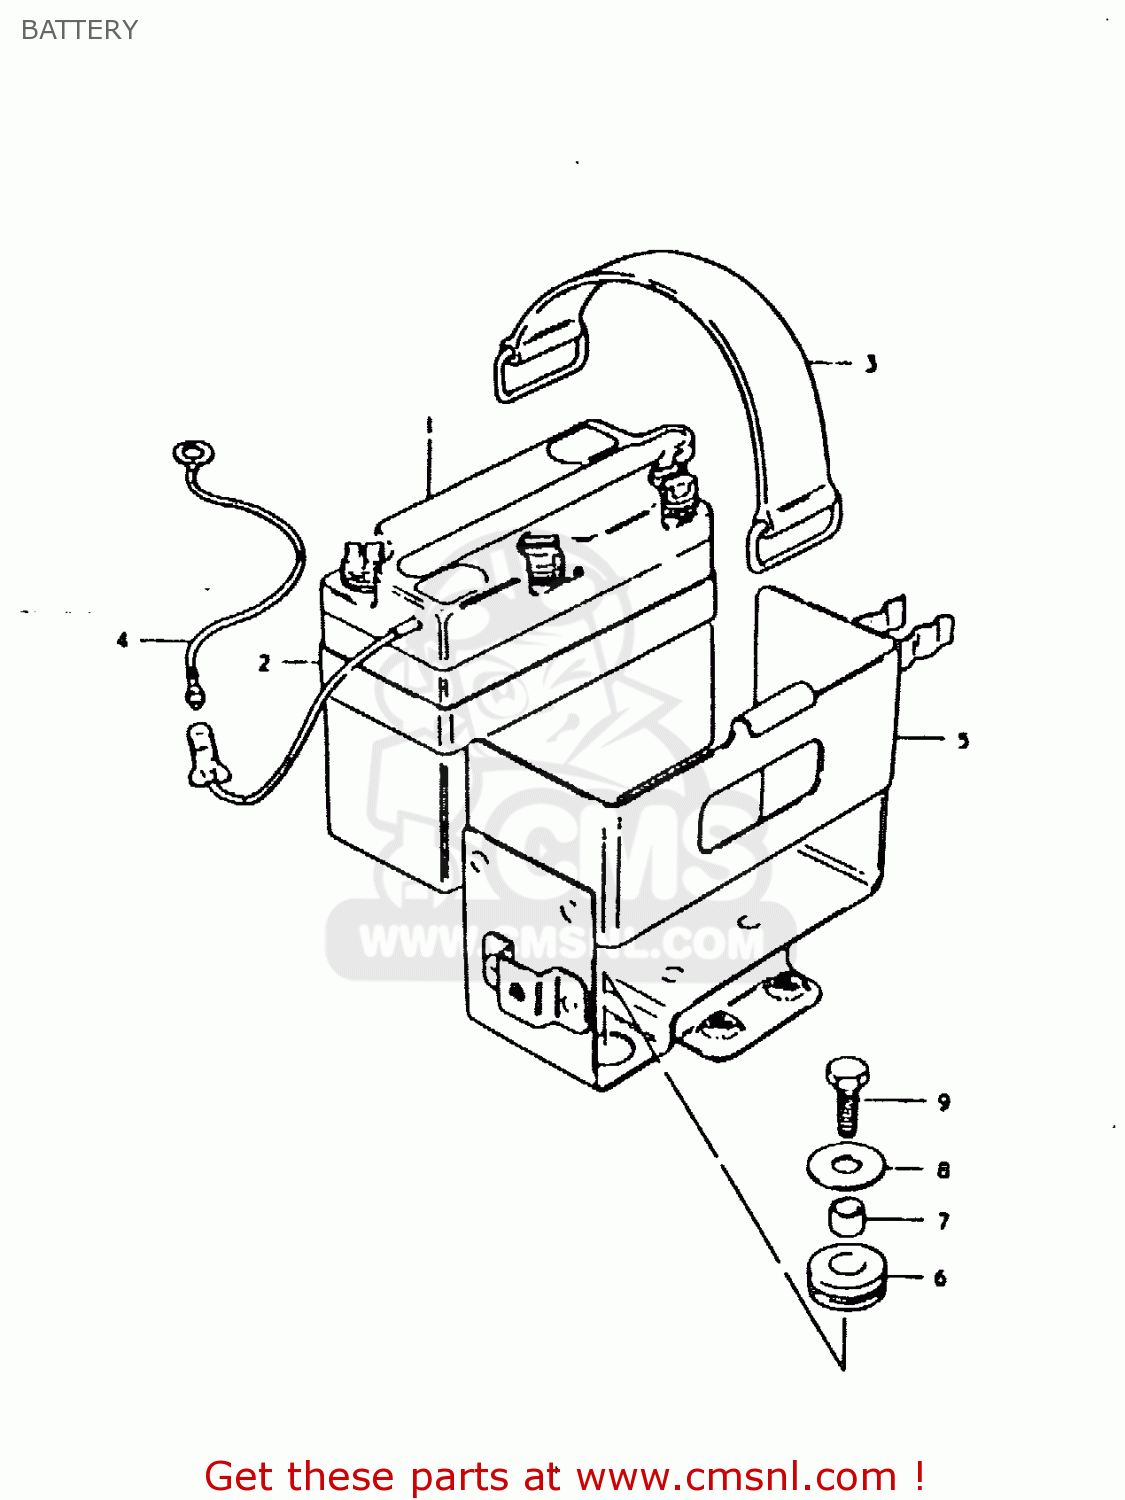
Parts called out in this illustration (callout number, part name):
1	BATTERY(6N4B-2A,6V4.2AH)
2	PROTECTOR,BATTERY
3	BAND
4	LEAD WIRE
5	HOLDER,BATTERY
6	CUSHION
7	SPACER (7X9X7)
8	WASHER (6.5X20X1.2)
9	BOLT, UPPER
